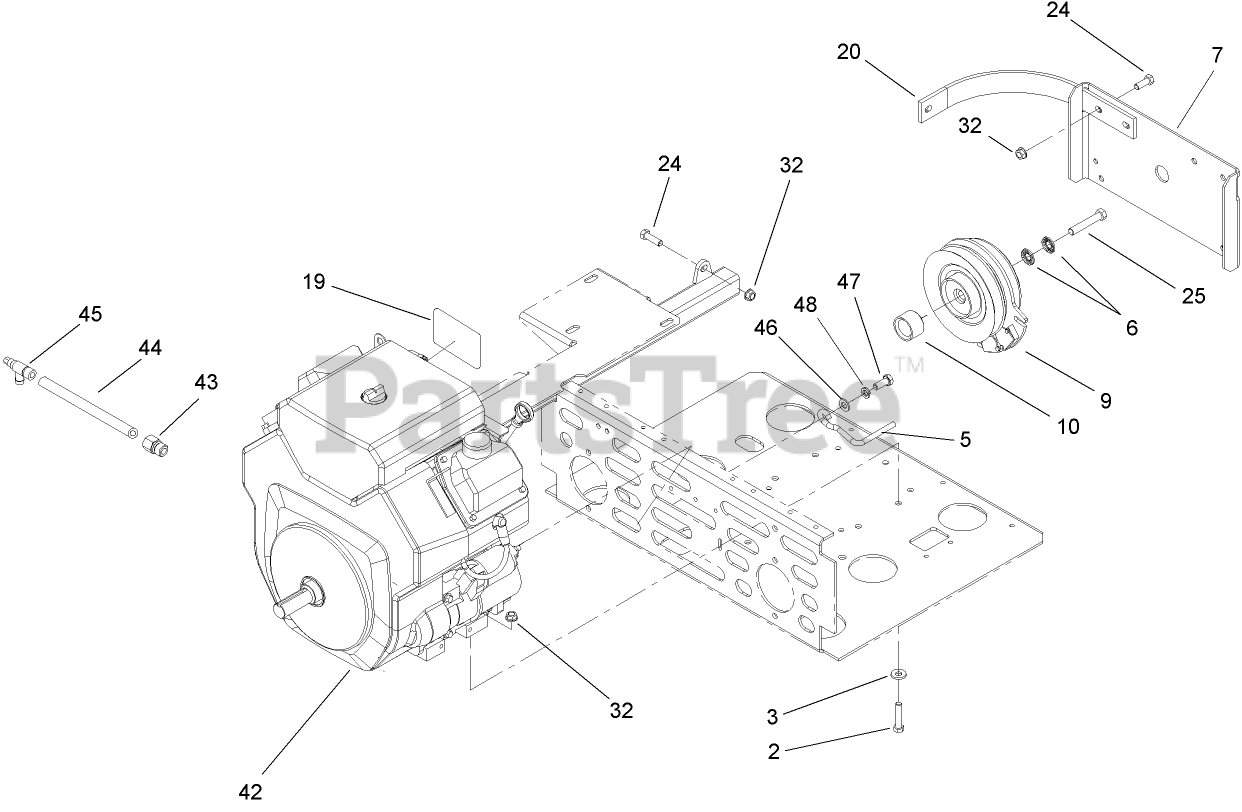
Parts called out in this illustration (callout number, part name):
2	SCREW-HH
3	WASHER-BELLEVILLE
5	ROD-BELT
6	WASHER-SPRING
7	GUARD-CLUTCH
9	CLUTCH
10	SPACER-CLUTCH
20	STRAP-GUARD
24	SCREW-HH
25	SCREW-HH
32	NUT-HHF, WHIZ
43	Adapter
44	Valve-Drain, Oil
45	HOSE-DRAIN, OIL
46	WASHER-FLAT
47	SCREW-HH
48	WASHER-BELLEVILLE
